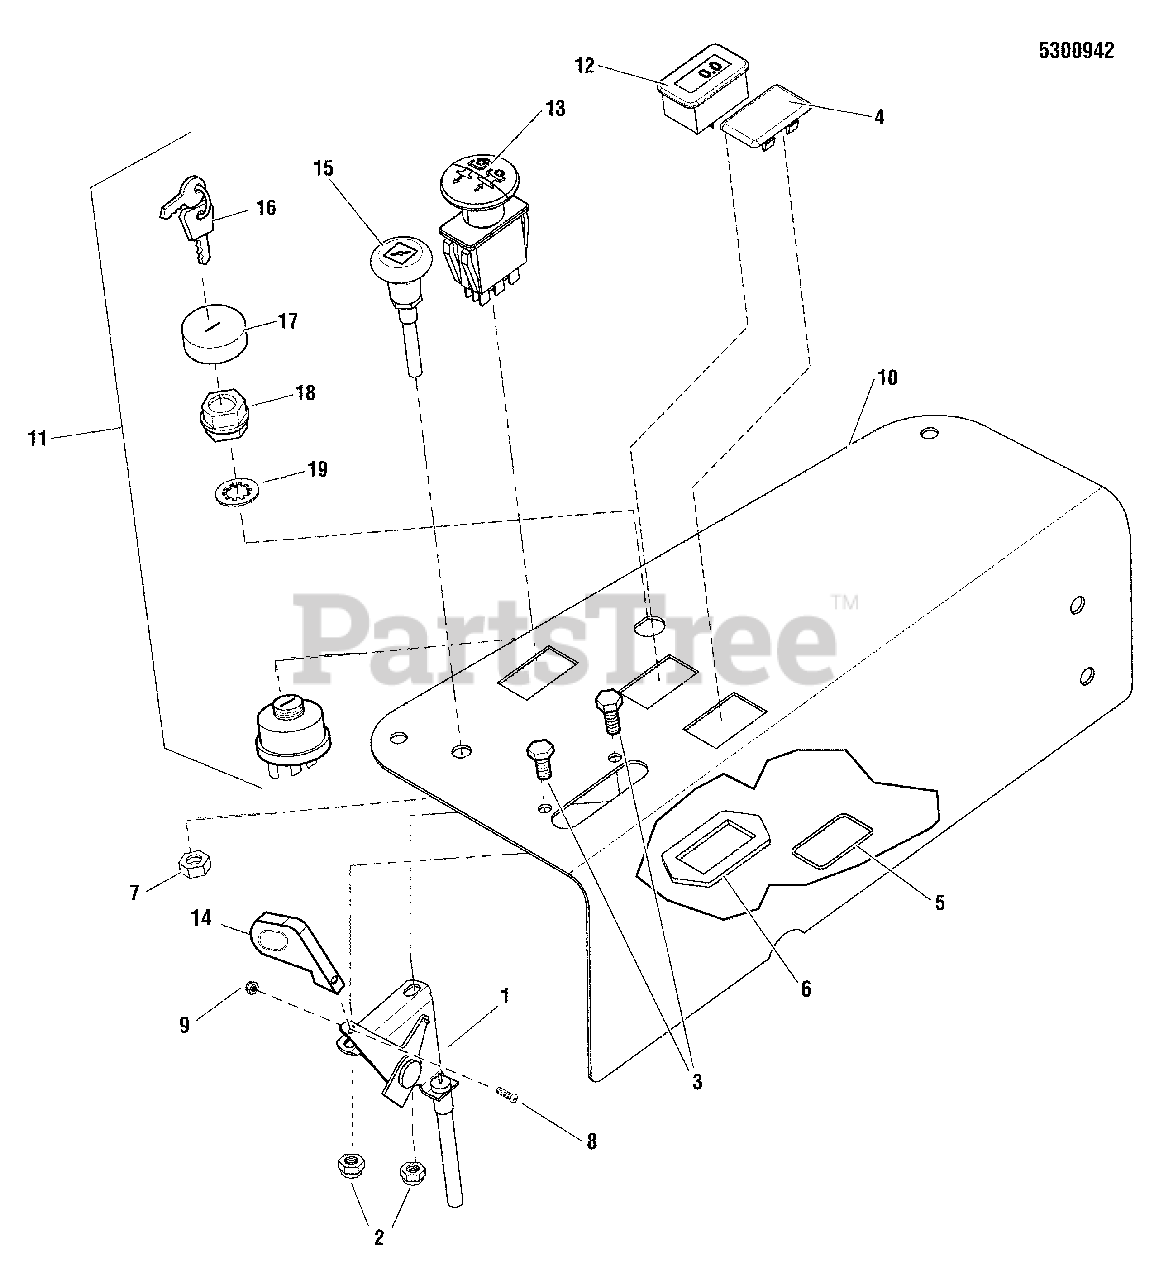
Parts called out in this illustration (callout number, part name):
1	CABLE, THROTTLE CONTROL, 37"
2	NUT, 1/4-20 HEX NYLON LOCK
3	BOLT, 1/4-20 X 3/4 GD5 YZ
4	PLUG, .820X1.44 HOLE, BLACK PLASTIC
5	O-RING, 7/8 ID X 1/16 W
6	RING, SWITCH RETAINER
7	NUT, 3/8-24 HEX
8	SCREW, #10-24 X 1" RS, CZ
9	NUT, #10-24 HEX NYLON LOCK
10	PLATE, CONTROL PANEL - BLACK
11	SWITCH ASMY-IGNITION INDAK NO KEYS/HDWR
12	HOUR METER, W/ SUPRESSOR
13	SWITCH, BLADE ENGAGEMENT
14	KNOB-SLOTTED THROTTLE
15	CABLE, CHOKE CONTROL, 51 (Z)
16	KEYS, BLISTER PK KIDS+MWRS DON'T MIX, DOM
16	KEYS, BLISTER PK KIDS+MWRS DON'T MIX, EXP
17	COVER, SWITCH
18	NUT, HEX FLANGE, 5/8-32 IGN SW DIE CAST
19	LOCKWASHER, INTERNAL TOOTH, .625 THIN BLK
